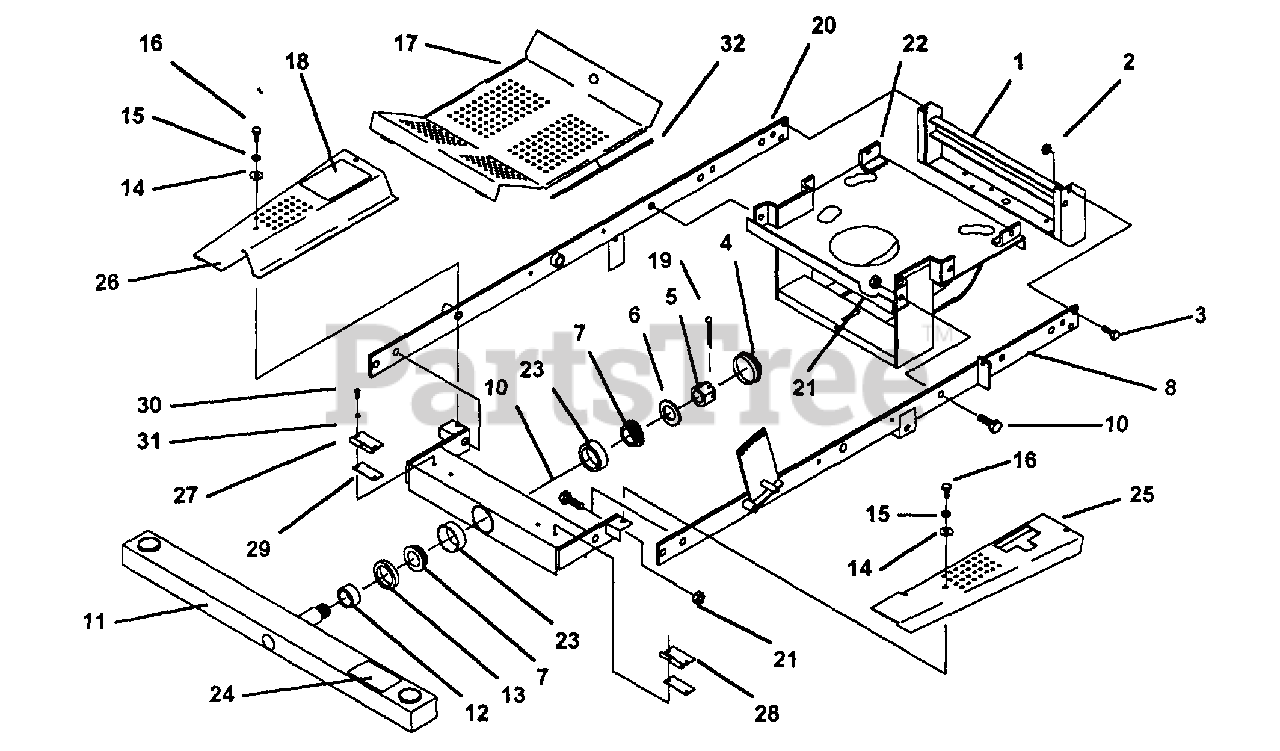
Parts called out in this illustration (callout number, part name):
1	REAR BUMPER WELDMENT
2	NUT, 3/8-16 NYLOC
3	BOLT, 3/8-16 X 1-1/4" GR.S
4	GREASE CAP
5	NUT, HEX. SLOTTED 1"-14
6	WASHER, 1" 10 GA.
7	BEARING CONE
8	FRAME SIDE WLDT., L.H.
10	BOLT, 1/2-13 X 1-1/4" GR.5
11	FRONT BUMPER/AXLE WELDMENT
12	BEARING SPACER
13	SEAL, OIL 1.688 SHAFT
14	WASHER, FLAT STD. 5/16"
15	LOCKWASHER, 5/16" HEAVY SPRING
16	BOLT, 5/16-18 X 3/4" GR. 5
17	FOOT DECK WELDMENT
18	DECAL, OPERATION INSTRUCTIONS
19	COTTER PIN, 3/16 X 2"
20	FRAME SIDE WLDT., R.H.
21	NUT, 1/2-13, STOVER
22	MOTOR MOUNT WELDMENT
23	BEARING CUP
24	DECAL, TOW WARNING
25	FOOT DECK SKIRT, LH
26	FOOT DECK SKIRT, RH
27	HINGE
29	HINGE SHIM PLATE
30	BOLT, 1/4-20 X 3/4" GR. 5
31	LOCKWASHER, 1/4" SPLIT SPRING
32	TRIM-LOC U CHANNEL 1/8 X 2 LIP
